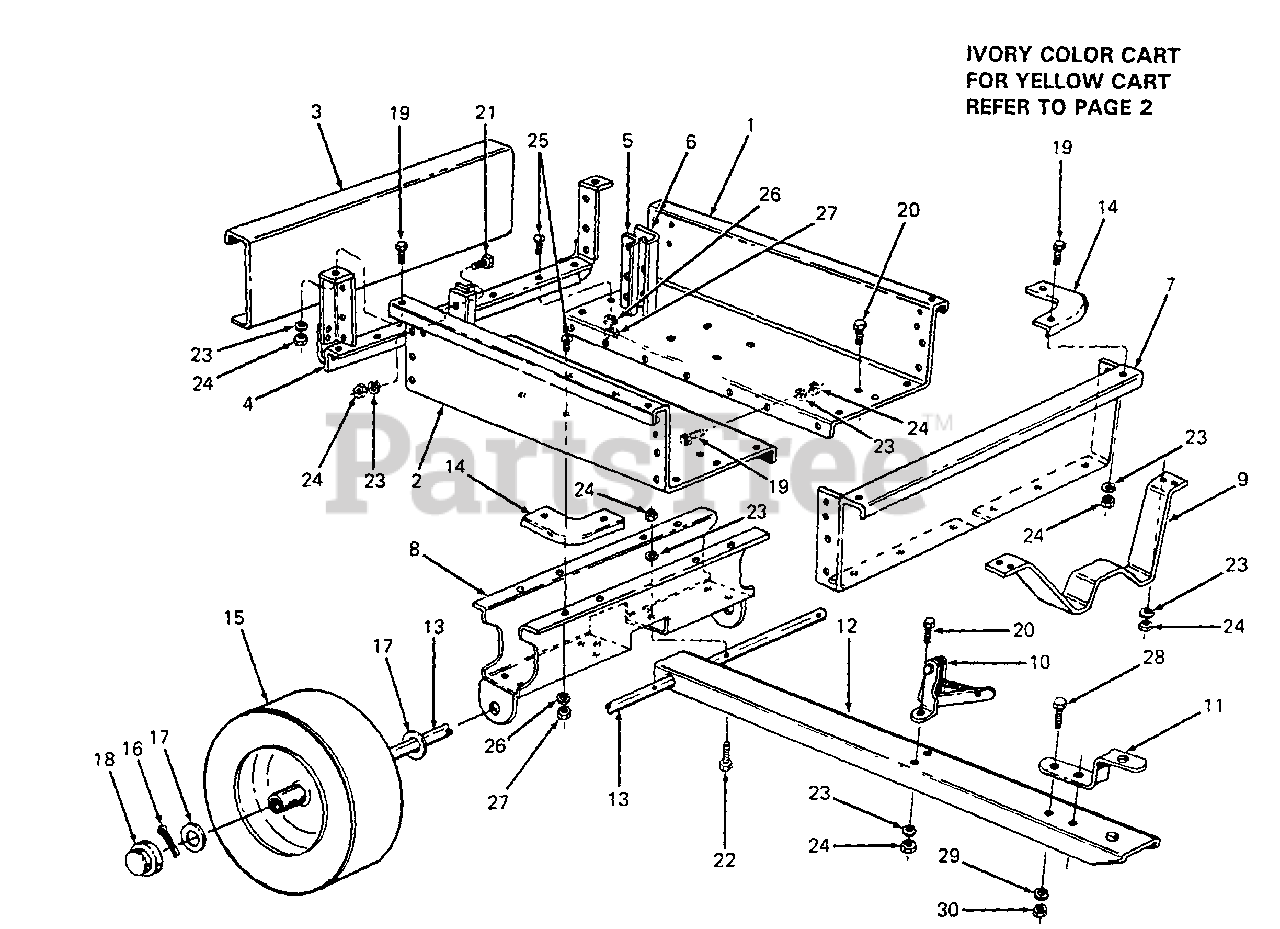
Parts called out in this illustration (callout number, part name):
6	Guide, Tailgate - Outside
17	Washer, Flat, 1.03 ID
18	Hub Cap
19	Screw, Hex Cap, 1/4-20 X .50 Lg
20	Screw, Hex Cap, 1/4-20 X .62 Lg
21	Screw, Hex Cap, 1/4-20 X .75 Lg
22	Screw, Hex Cap, 1/4-20 X 1.75 Lg
23	Washer, Lock, 1/4
24	Nut, Hex, 1/4-20
25	Screw, Truss Hd, 5/16-18 X .75 Lg
26	Washer, Lock, 5/16
27	Nut, Hex, 5/16-18
28	Screw, Hex Cap, 3/8-16 X 1.0 Lg GR5
29	Washer, Lock, 3/8
30	Nut, Hex, 3/8-16
